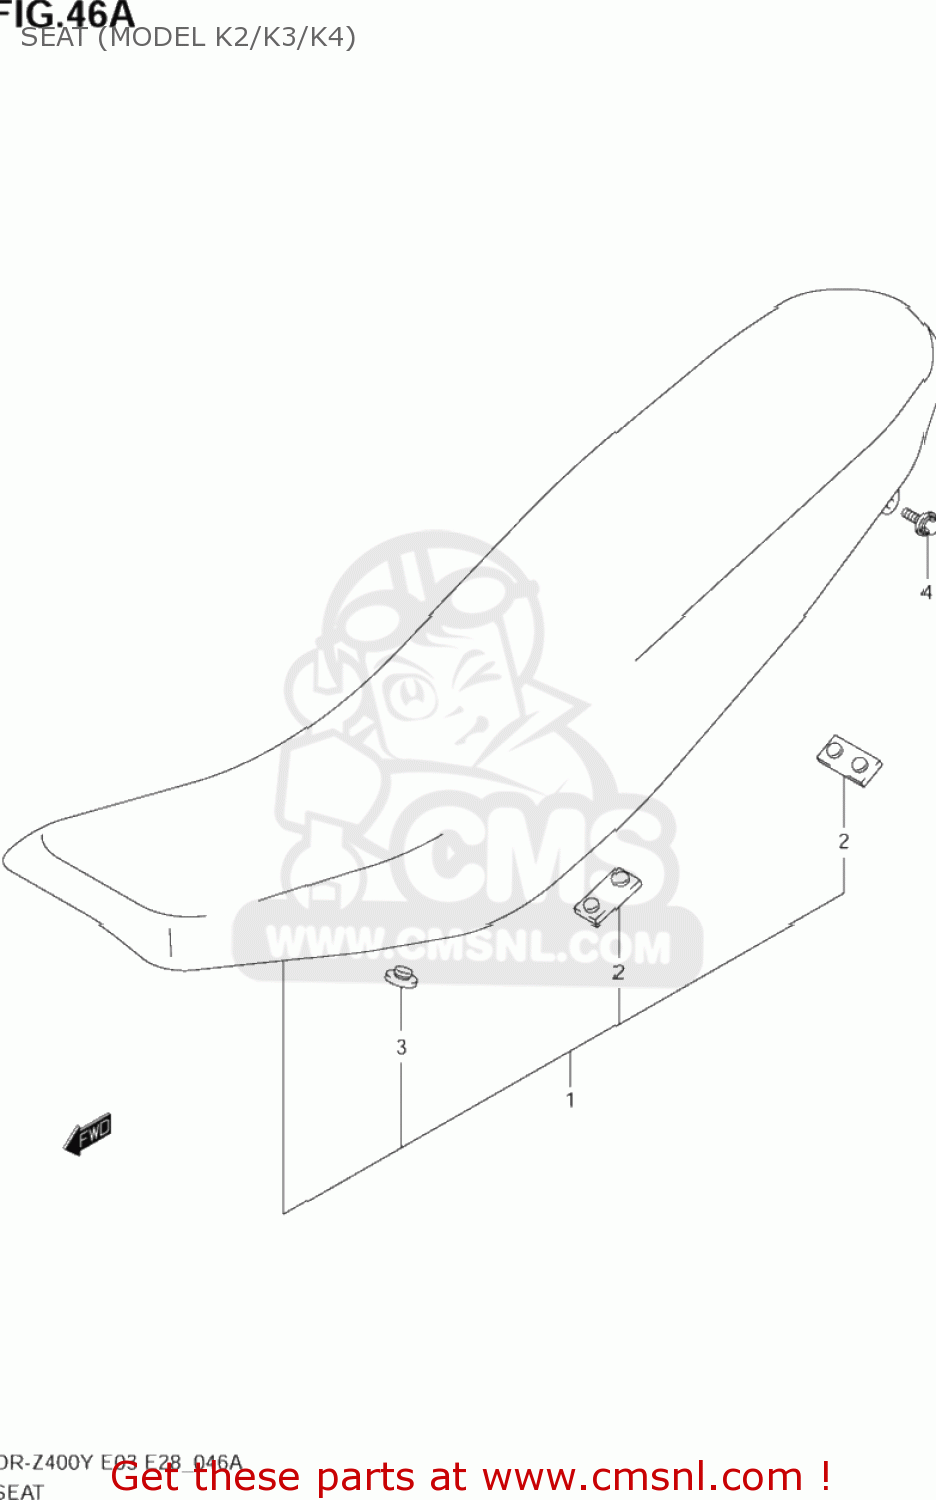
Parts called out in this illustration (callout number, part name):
1	SEAT ASSY(BLACK)
2	CUSHION,SEAT(40X20X6)
3	CUSHION
4	BOLT(6X20)
